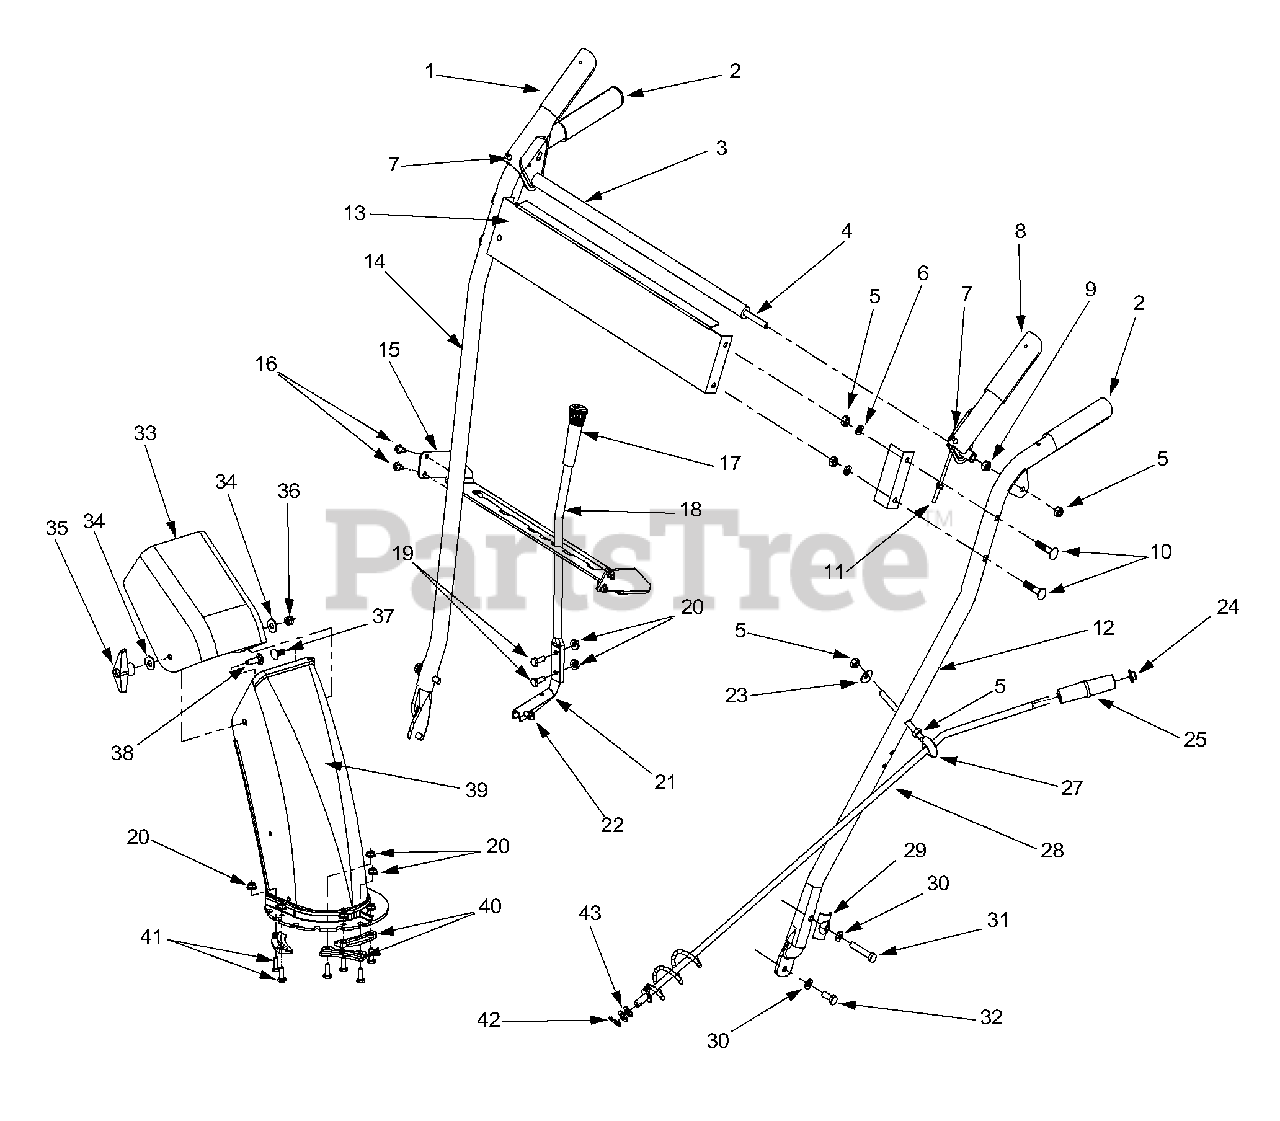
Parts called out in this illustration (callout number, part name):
1	Clutch Lever Assy - RH
3	Pivot Rod Cover
4	Pivot Rod
5	Hex Nut 5/16-18
6	Lock Washer 5/16
7	Rubber Bumper
8	Clutch Lever Assy - LH
9	Lock Hex Nut 1/4-20
10	Carriage Bolt 5/16-18 x 1.50
11	"Z" Fittings For Control Cables
16	Hex Washer Screw 1/4-20 x .50
19	Hex Cap Screw 1/4-20 x .75
20	Hex Lock Nut 1/4-20
21	Shift Lever Spring
22	Hex Washer Screw 1/4-20 x 1.0
23	Bell Washer
24	Push Cap
25	Chute Knob
27	Eyebolt
28	Chute Directional Control Assembly
29	Handle Tab
30	Lock Washer 5/16
31	Hex Cap Screw 5/16-18 x 1.75
32	Hex Cap Screw 5/16-18 x .75
33	Upper Chute
34	Washer 5/16
36	Hex Lock Nut 5/16-18
37	Carriage Bolt 5/16-18 x .75
38	Carriage Screw 5/16-18 x 1.0
39	Lower Chute
40	Flange Keeper
41	Hex Cap Screw 1/4-20 x .75
42	Cotter Pin
43	Flat Washer 3/8
